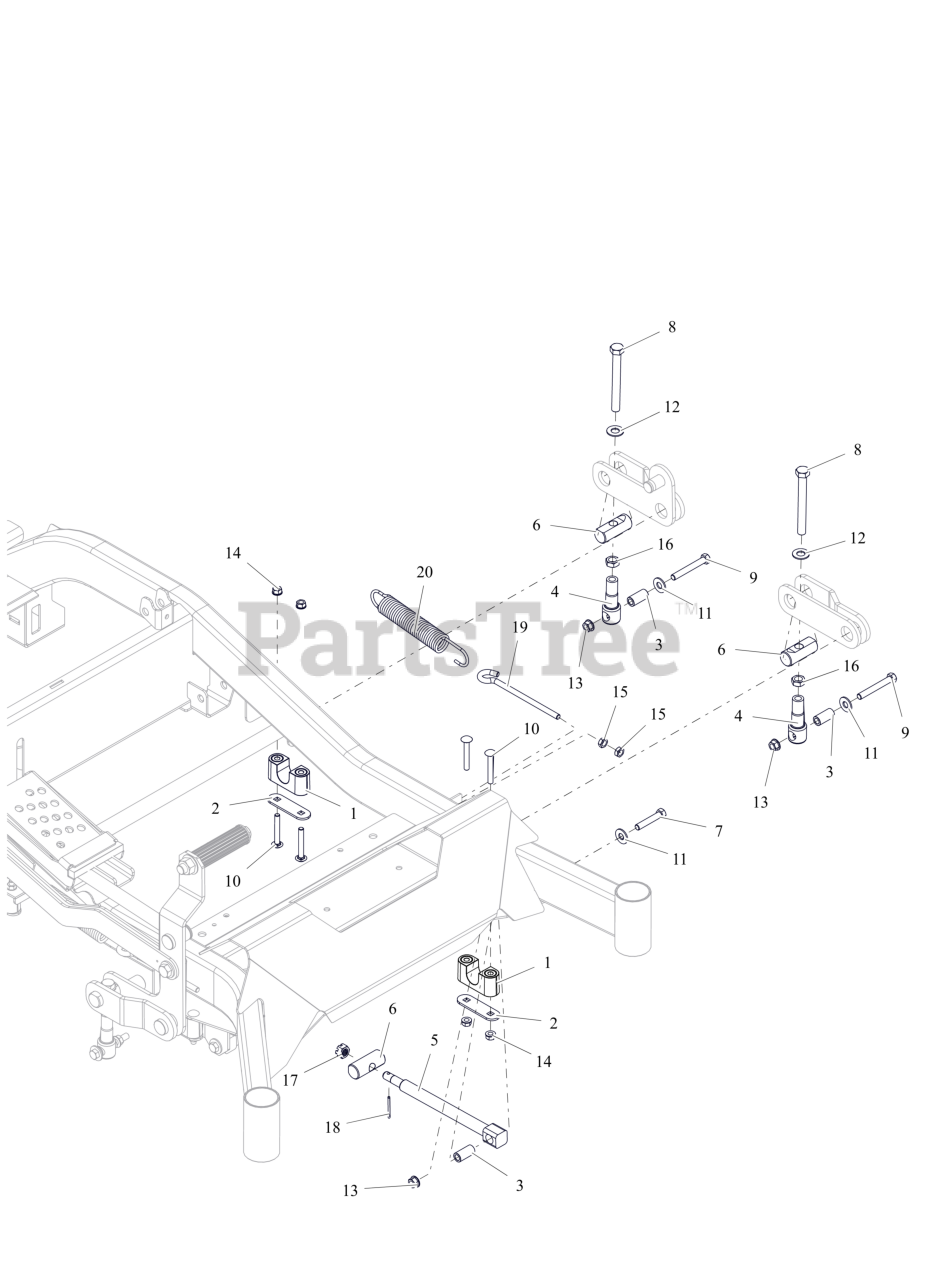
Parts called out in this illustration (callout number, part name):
1	ASM-BUSHING, DECK LIFT
2	PLATE, BEARING SUPPORT
3	SPACER, DECK LEVELING
4	LINK, DECK LIFT FORMED
5	DRAG,LINK-HD
6	PIN, DECK LIFT
7	BLT,HEX .38-16X2.00 G5 ZCC
8	BLT, HEX .50-13X4.50F G8 ZCC
9	BLT, HEX .38-16X2.75 G8 ZCC
10	BLT, RHSSN.31-18X2.25 G5 ZCC
11	WSHR,FLT .438X1.00X.083 ZCC
12	WSHR, FLT .557X1.040X.102 ZCC
13	NUT-LK-TOP-FLG .38-16 ZC120
14	NUT,LK-CTR-FLG .31-18 GF ZCC
15	NUT-JAM .375-16 G2 ZCC
16	NUT-JAM .500-13 G2 ZCC
17	NUT-SL .50-13
18	PIN,CTR.12X1.25EXTPRSQCT ZC120
19	BOLT,.38-16 X 5.25-.62 DIA EYE
20	SG-TENS .162X1.25X8.25 WLD 25
